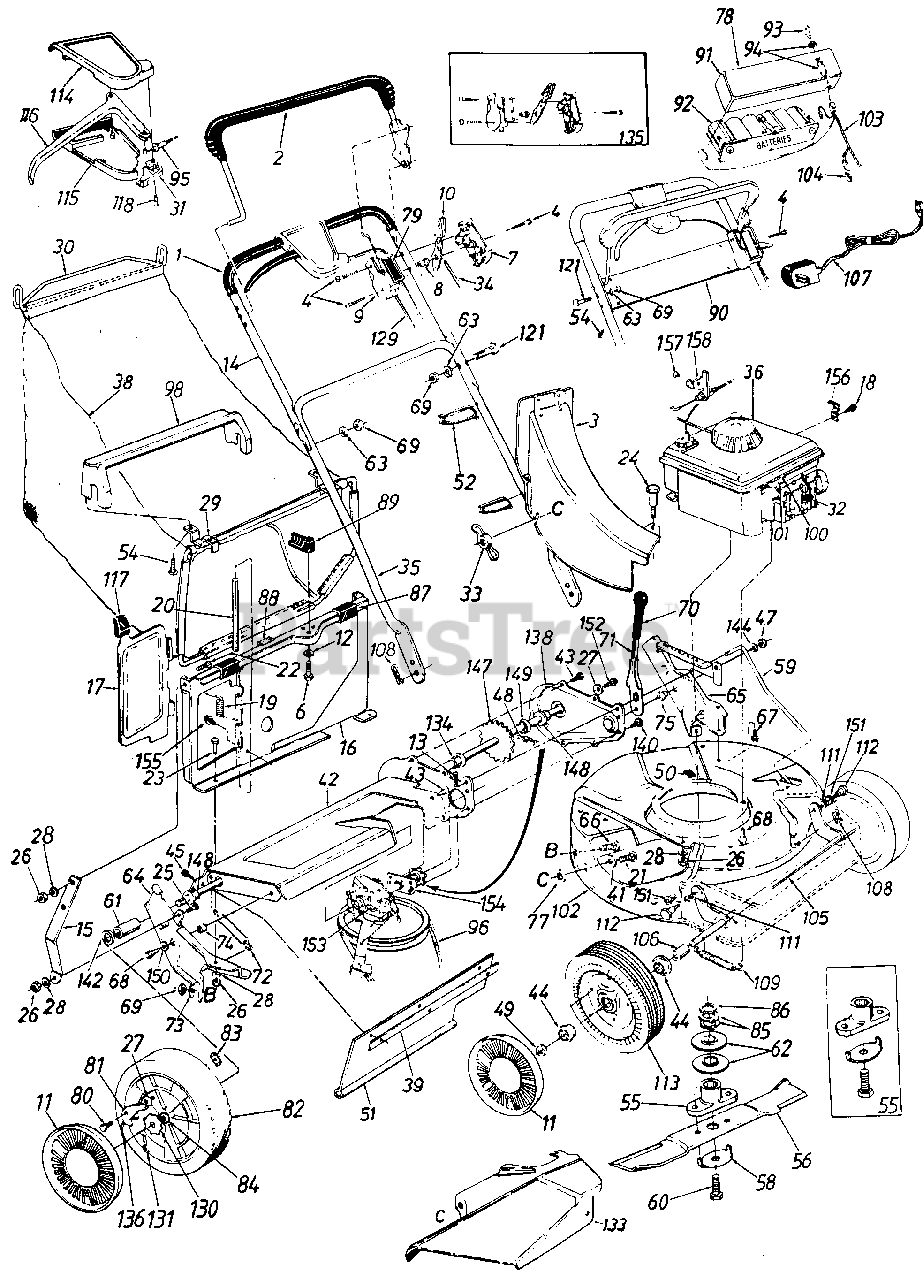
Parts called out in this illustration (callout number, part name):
1	GRIP-SHRINK-25 IN
3	CHUTE ASSY-TOP DISCH
4	SCREW-TRUSS MACH
6	SCREW-HEX 1/2-13X1.00
6	SCREW-HEX WASH 1/4-20X.75
7	SCREW-HEX WASH 1/4-20X.75
7	PANEL HALF-CONTROL
8	PIN-CONTROL DISC
9	PANEL HALF-CLUTCH
10	LEVER-THROTTLE CONT-REV
11	HUB CAP
12	WASHER-SHAKE PROOF
13	PIN-COTTER-3/32 DIA X .75
14	HANDLE-UPPER-CHROME
15	BRACKET-PANEL SUP
16	PANEL ASSY-CATCHER
17	DOOR-TOP DISCHARGE
18	SCREW-HEX B-TAP #10 X .38
19	SPRING-TORSION
21	BOLT-CARRIAGE 1/4-20 X .62
22	SCREW-TRUSS MACH
23	SCREW-HEX 1/4-20 X .50
24	SCREW-SHLD
25	SCREW-HEX 1/4-20 C .62
26	NUT-HEX 1/4-20
27	WASHER-SPRING BELL
28	LOCK WASHER 1/4 DIA
29	FRAME-GRASSCATCHER
30	ROD-HGT ADJ
30	HANDLE-GRASSCATCHER
31	CAP-CABLE MTG
32	INSULATOR-SPARK PLUG
33	NUT-WING
34	WIRE-THROTTLE 58 LG
35	HANDLE-LOWER PAINTED
38	BAG-GRASS-CONV
39	STRIP-RETAINING
41	WASHER-FL-.344 ID X .62 OD X .033
42	AXLE ASSY-CHAIN
43	SCREW-HEX B-TAP 1/4 X .38
44	BEARING-BALL
45	SCREW-HEX WASH HD
47	NUT-HEX LOCK 3/8-24
48	#48 CHAIN 1/2 PITCH
49	NUT-HEX INS L-1/2-20
51	FLAP-RR
52	TIE-CABLE
54	SCREW-TAP .215 X 1
55	KIT-BLADE ADAPTER-SPLINED
56	BLADE-21IN
58	KIT-BLADE MOUNTING
59	ROD-HGT ADJ 1.50 X 19.42
60	SCREW-HEX 7/16-20 X 1.50
61	SPACER-.513 ID X .703 OD X .69
62	PULLEY HALF-SERRATED
63	WASHER-LOCK-5/16
64	BRACKET ASSY-HDLE-RH
65	BRACKET ASSY-HDLE-LH
66	BOLT-CARRIAGE 5/16-18 X .62
67	SCREW-HEX WASH HD 5/16-18X1/2
68	SCREW-HEX
69	NUT-HEX 5/16-18
71	LEVER-HGT ADJ
72	SPRING-EXTENSION
73	WASHER-BELL .337 X .867 X .057
75	SPACER-SHLD .500 X .100
77	RETAINER-BOLT 1/4X.50 OD
78	STARTING LABEL
80	SCREW-SHLD .342 DIA X .268
81	PAWL
82	WHEEL ASSY W/TIRE
83	NUT-FLAT WELD 1/4 X 20
85	WASHER-WAVE
86	WASHER-SERRATED
87	CLIP-PANEL BAG
88	STRIP-FOAM 1/4X1.0
89	KNOB-LOCKING
90	TRAY-BATTERY-LOWER
91	TRAY-BATTERY-UPPER
92	BATTERY PACK
93	KEY-IGN (SET OF TWO)
94	SWITCH-KEY
95	CABLE-CLUTCH X 50.0
96	BELT-V 3/8 X 31.0
98	HANDLE-BAG-BLACK
100	SCREW-HEX WASH HD TAP
101	CLIP-CASING
104	PLUG
105	AXLE ASSY-FR-290
107	CHARGER-BATTERY
108	PIN-INTERN COT-5/16 DIA
109	SPRING-EXTENSION
111	WASHER-INTERN L 3/8 X.56 OD X .018
112	SCREW-SHLD
113	WHEEL ASSY W/TIRE 7X1.75BB
114	COVER-HALF-CONTROL
115	COVER-HALF CONT-LWR
116	LEVER-CONTROL
117	KNOB
118	SCREW-FL C-SUNK AB
121	BOLT-CARRIAGE-CURV 5/16-18 X 1.38
129	CABLE-CONTROL
130	RATCHET
131	PIN-COTTER-1/8 DIA X 1.00
133	DEFLECTOR-CHUTE
134	BEARING-HEX FLANGE
135	KIT-THROTTLE CONTROL
136	SPRING-NYLON
138	COVER-CHAIN
140	SCREW-HEX WASH SF TAPP
142	WASHER-FL
144	WASHER-FL-.385 ID X .87 OD X .06
147	SHAFT ASSY-REAR
148	BEARING-HEX FLANGE .506 ID
149	WASHER-FL-.531 X .930 OD X .050
150	WASHER-FL-.531 ID X 1.25 OD X 1.00
151	BEARING-NYLINER
152	SCREW-1/4-20 X .62
153	TRANSMISSION-COMP
154	BEARING-CUP HEX
155	XXX
155	SCREW-HEX B-TAP #10 X .38
156	CLAMP-CASING
158	BRACKET-CABLE
